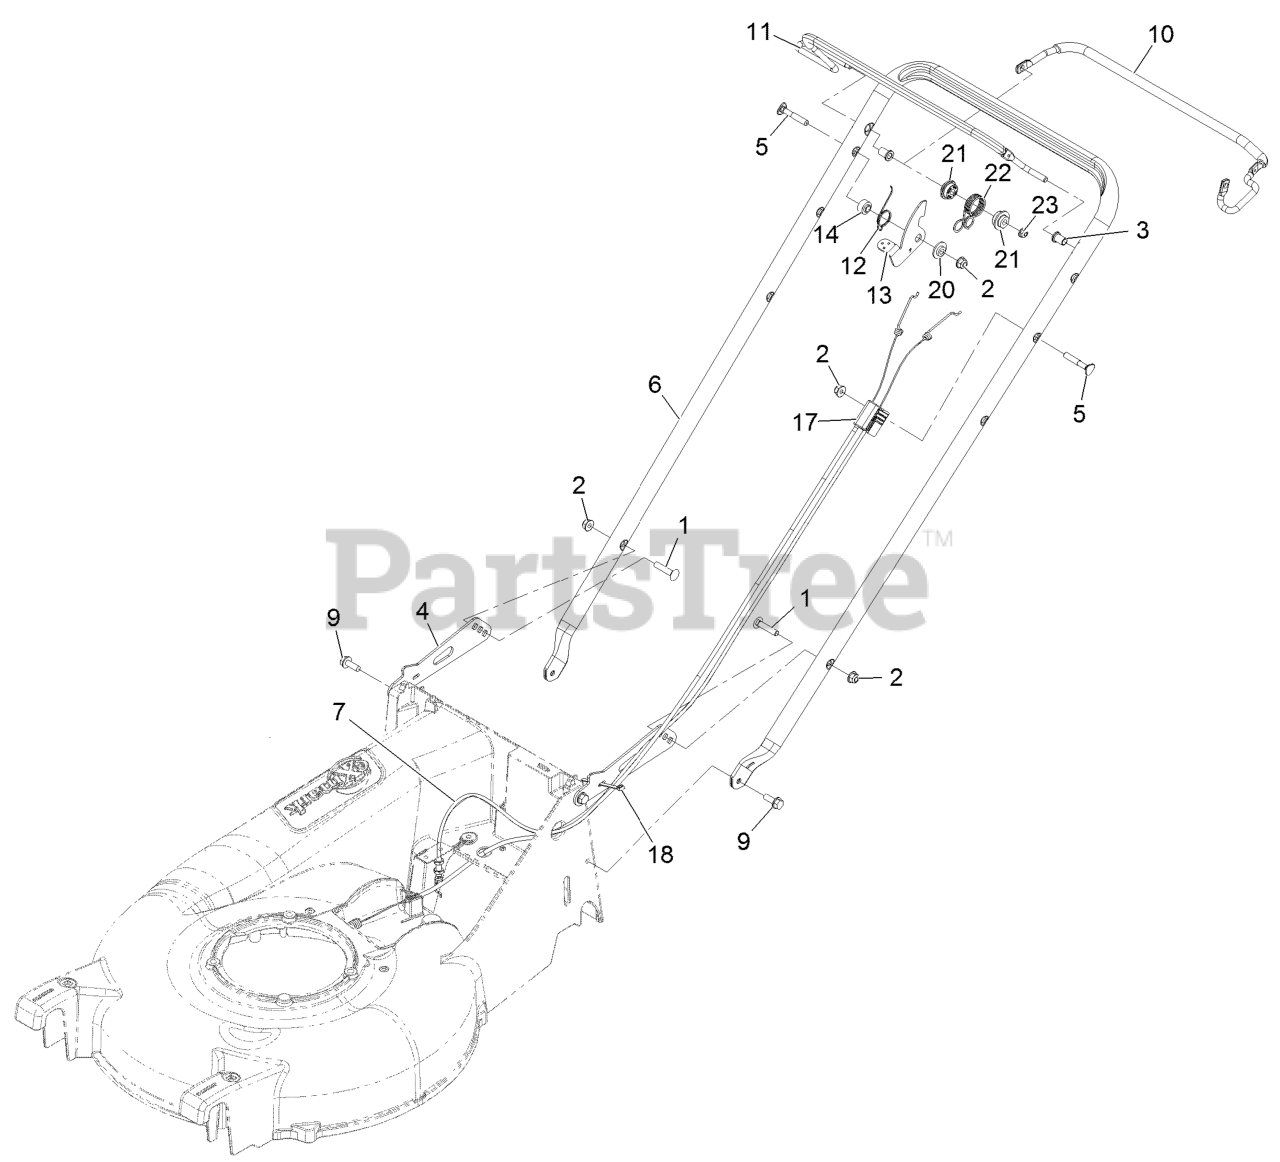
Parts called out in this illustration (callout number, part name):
1	BOLT-CARR
2	NUT-HF, NI
3	BUSHING-HANDLEBAR
4	BRACKET,HANDLEBAR
6	HANDLEBAR-P21
9	SCREW-TAPTITE
10	BAIL-DRIVE COATED
12	SPRING-LEVER, BBC
13	LEVER-BBC
14	BUSHING-STEPPED
17	CABLE-BBC
18	TIE-CABLE
20	WASHER-STEPPED
21	BUSHING-SPRING, PIVOT
22	SPRING,BBC RETURN
